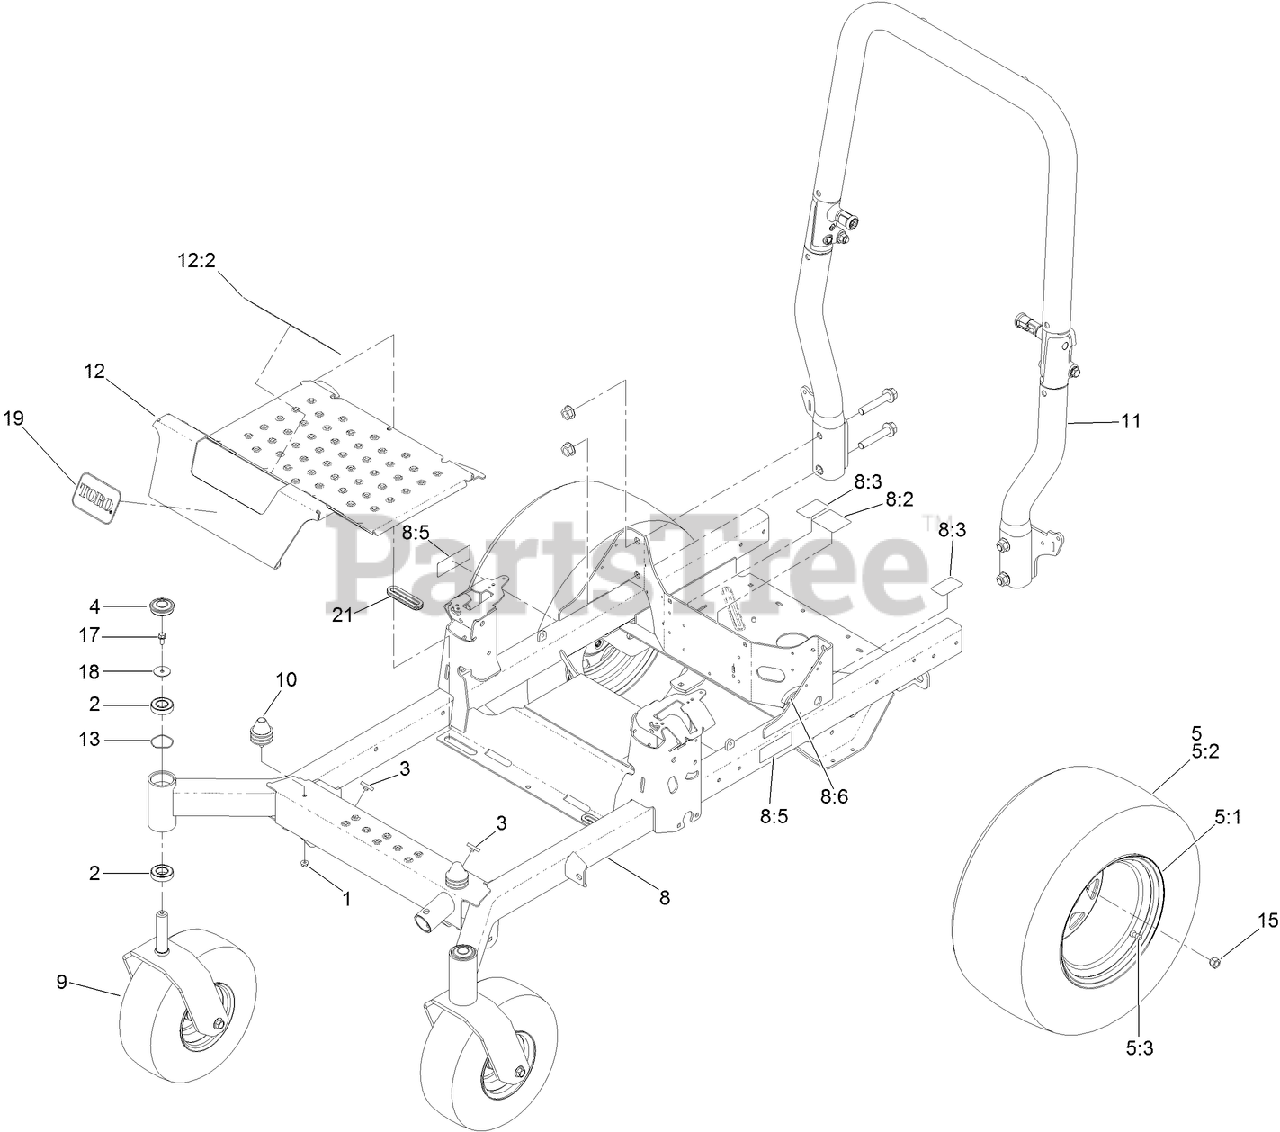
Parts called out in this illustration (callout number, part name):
1	NUT-HF, NI
2	BEARING-BALL
3	BUMPER-PUSH-IN, RUBBER
4	CAP-GREASE
5	WHEEL AND TIRE ASM
5:1	RIM-WHEEL
5:2	TIRE
5:3	STEM-VALVE
8	FRAME ASM
8:2	DECAL-ROUTING, BELT
8:3	DECAL-RELEASE, DRIVE
8:5	DECAL-WARNING
8:6	STRIP-SEAL
9	FRONT CASTER ASM (W/FORK)
10	ISOLATOR
11	ROPS ASM
12	PAN-FLOOR
12:2	DECAL-DANGER
13	SPRING
15	NUT-LUG
17	SCREW-HHF
18	WASHER-FLAT
19	DECAL
21	GROMMET-RUBBER
